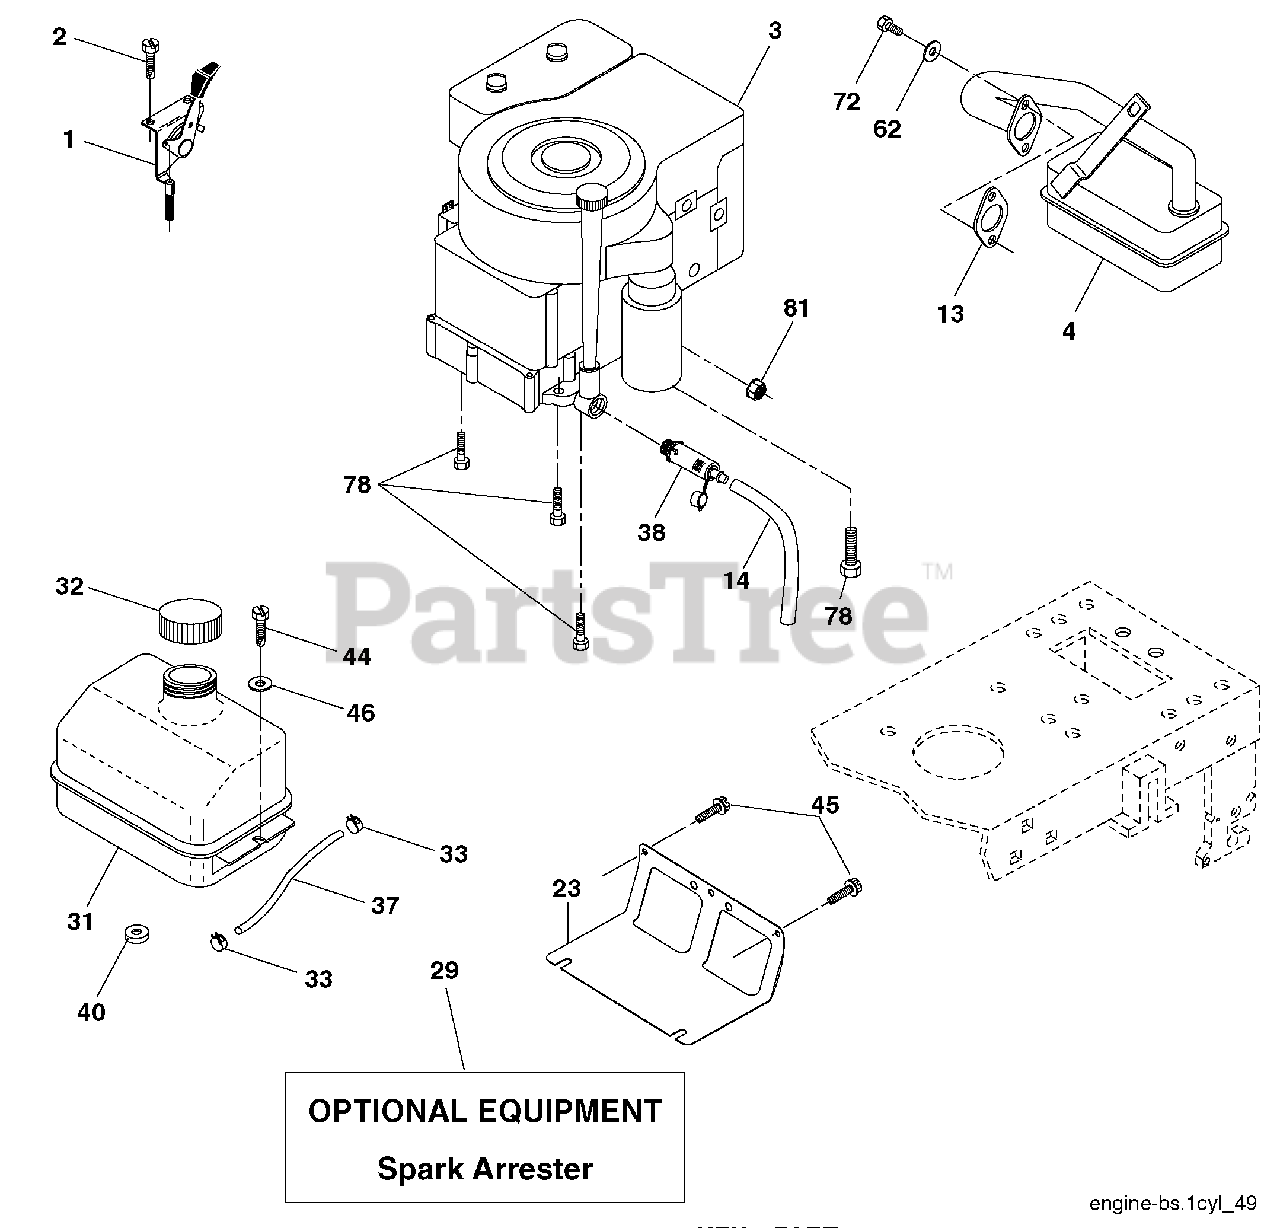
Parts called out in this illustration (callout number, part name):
1	Control, Throttle
2	Screw Hex Thd Cut 1/4-20 x 1/2
4	Muffler
13	Muffler Gasket
14	Tube Oil Drain
23	Shield, Browning/Debris Guard
29	Arrester, Spark
32	Cap, Fuel
33	Clamp, Hose Blk
37	Line, Fuel
38	Plug Drain Oileasy
44	Screw Hex Wsh Thdrol 1/4-20 x 3/4
45	Screw Hex Wsh Thdrol 3/8-16 x 3/4
46	Washer 9/32 x 7/8 x 16 Ga.
62	Washer Split
72	Screw Socket Hd 5/16-18 x .75
78	Screw 3/8-16 x 1-1/4
81	Nut Keps Hex 1/4-20 unc
